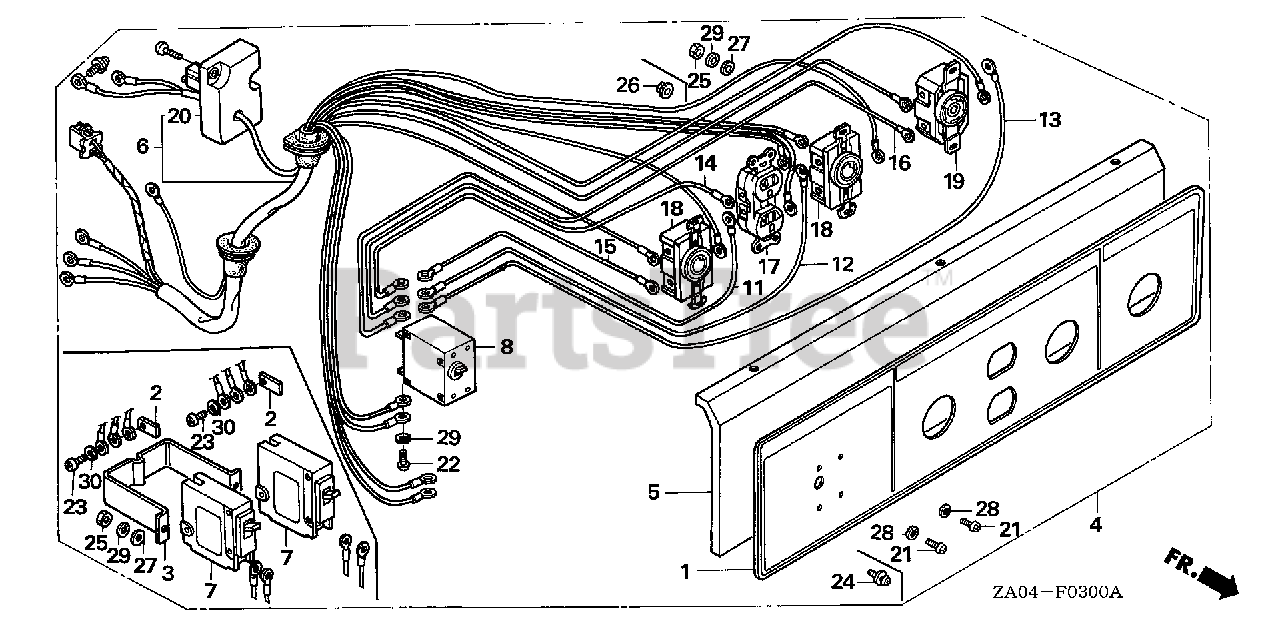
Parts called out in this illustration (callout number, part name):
1	MARK, RECEPTACLE PANEL (NOT AVAILABLE)
2	TERMINAL, BREAKER
3	SUPPORT, BREAKER
4	PANEL ASSY., RECEPTACLE *B9* (ATLANTIS BLUE)
5	PANEL, RECEPTACLE *B9* (ATLANTIS BLUE) (NOT AVAILABLE)
6	HARNESS ASSY., RECEPTACLE (NOT AVAILABLE)
7	BREAKER, CIRCUIT (22A)
11	WIRE, RECEPTACLE CIRCUIT BREAKER CONNECTING
12	WIRE, RECEPTACLE CIRCUIT BREAKER CONNECTING
13	WIRE, RECEPTACLE CIRCUIT BREAKER CONNECTING
14	WIRE, RECEPTACLE CIRCUIT BREAKER CONNECTING
15	WIRE, RECEPTACLE CIRCUIT BREAKER CONNECTING
16	WIRE, RECEPTACLE CIRCUIT BREAKER CONNECTING
17	RECEPTACLE ASSY. (20A/125V) (MATSUSHITA)
17	RECEPTACLE (20A/125V)
18	RECEPTACLE (20A/125V) (NOT AVAILABLE)
19	RECEPTACLE (30A/125-250V)
20	CONTROL UNIT, IDLE
23	SCREW, PAN (5X10)
25	NUT, HEX. (4MM)
27	WASHER, PLAIN (4MM)
29	WASHER, SPRING (4MM)
30	WASHER, SPRING (5MM)
